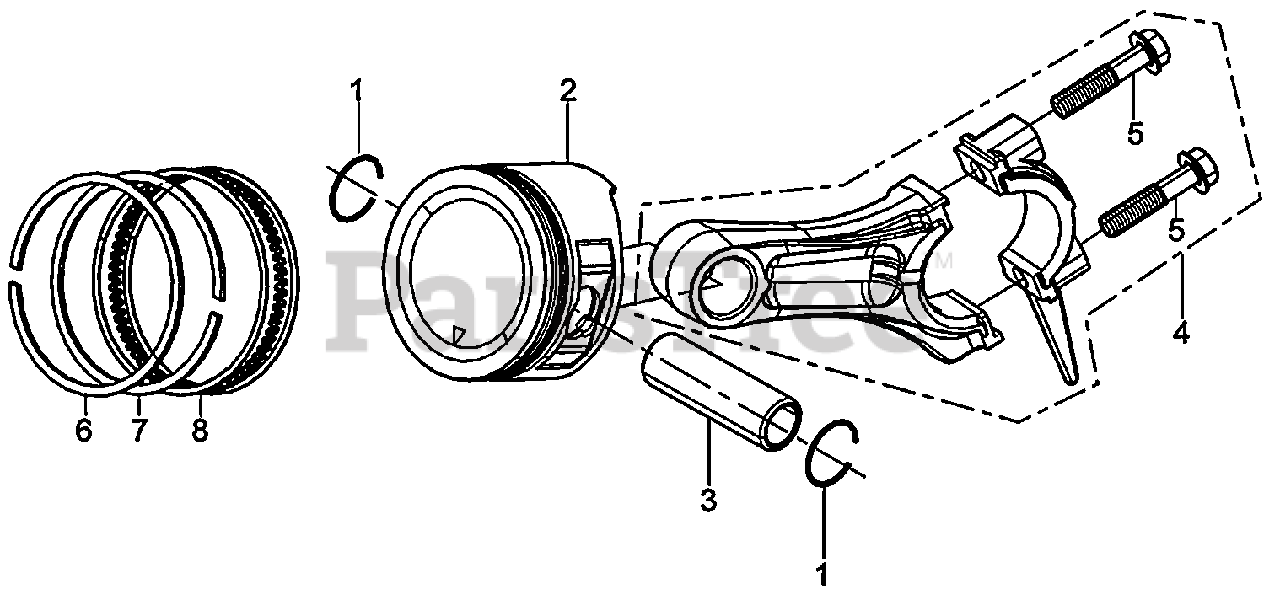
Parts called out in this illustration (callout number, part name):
1	CLIP, PISTON PIN
3	PIN, PISTON
4	ROD, CONNECTING
6	RING, THE FIRST
7	RING, THE SECOND
8	RING SET, OIL
